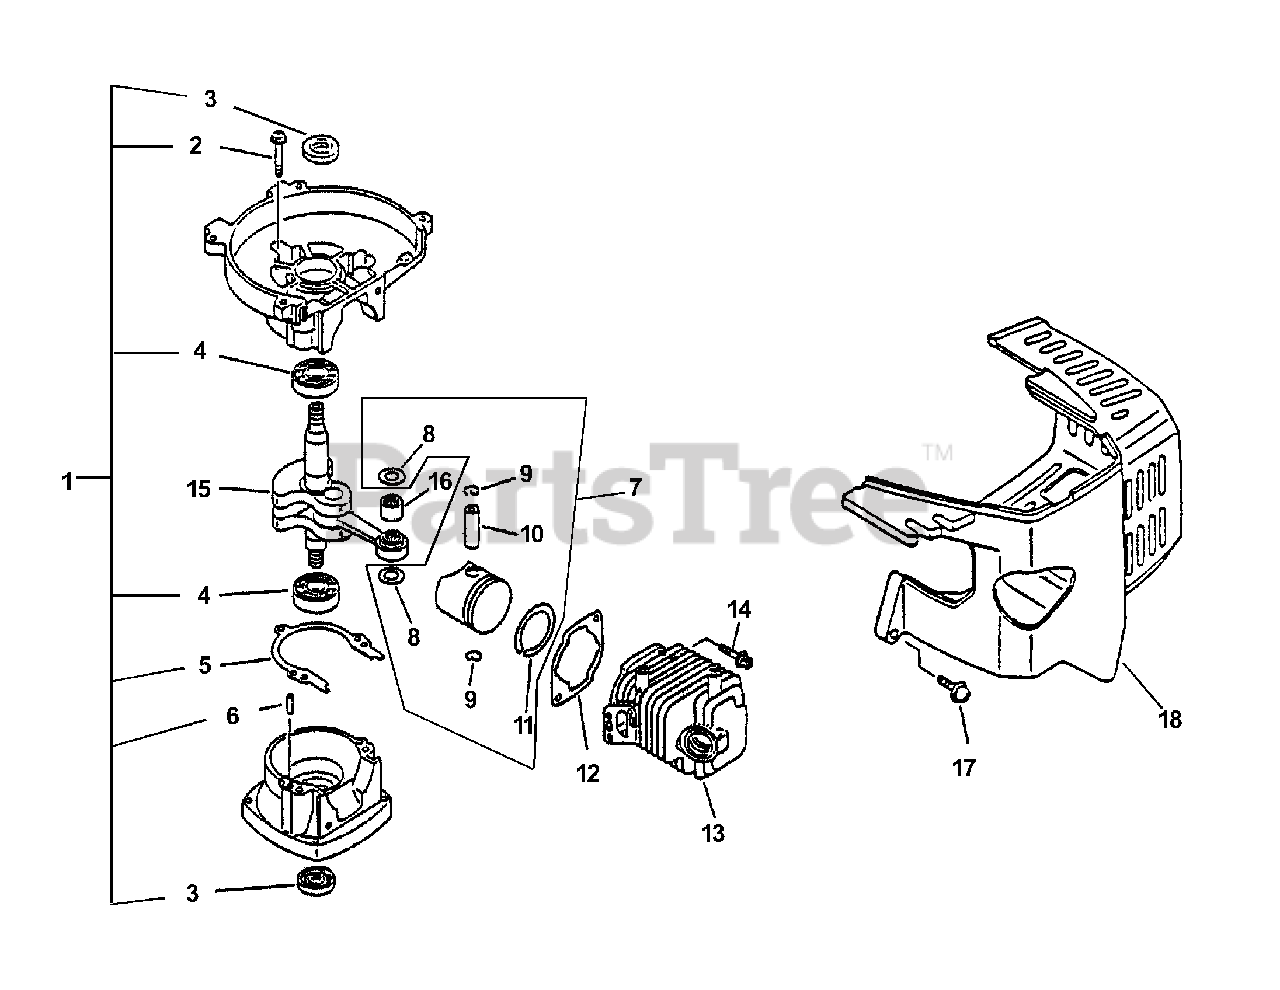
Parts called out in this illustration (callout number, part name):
1	CRANKCASE KIT
2	BOLT 5×28
3	SEAL, OIL 12
4	BEARING, BALL - 6201 C3
5	GASKET, CRANKCASE
6	PIN, LOCATING 4
7	PISTON KIT
8	WASHER, THRUST
9	RING, SNAP
10	PIN, PISTON 8
11	RING, PISTON
12	GASKET, CYLINDER
14	BOLT 5×22
15	CRANKSHAFT ASSY
16	BEARING, NEEDLE
17	SCREW 4×20
18	COVER, ENGINE
